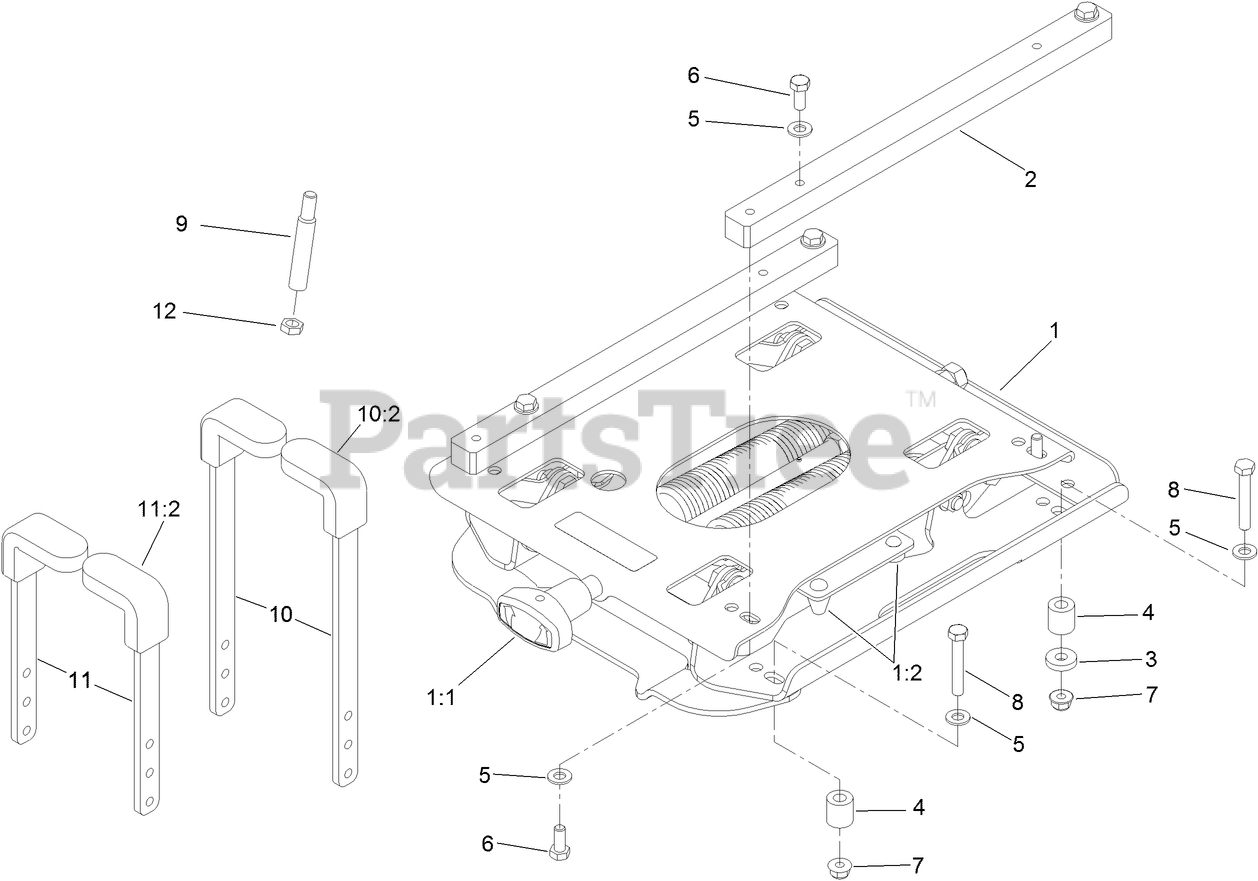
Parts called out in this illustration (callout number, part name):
1	SEAT-SUSPENSION
1:1	RUBBER STOPS KIT
1:2	ADJUSTMENT KNOB KIT
2	ADAPTER-MOUNT, SEAT
3	SPACER
4	SPACER-STRAP, CLUTCH
5	WASHER-PLAIN
6	SCREW-HH
7	NUT-HF, NI
8	SCREW-HH
9	SPEED CONTROL EXTENSION
10	EXTENDED HANDLE ASM
10:2	GRIP-HANDLE, STEERING
11	HANDLE ASM
11:2	GRIP-HANDLE, STEERING
12	NUT-JAM
